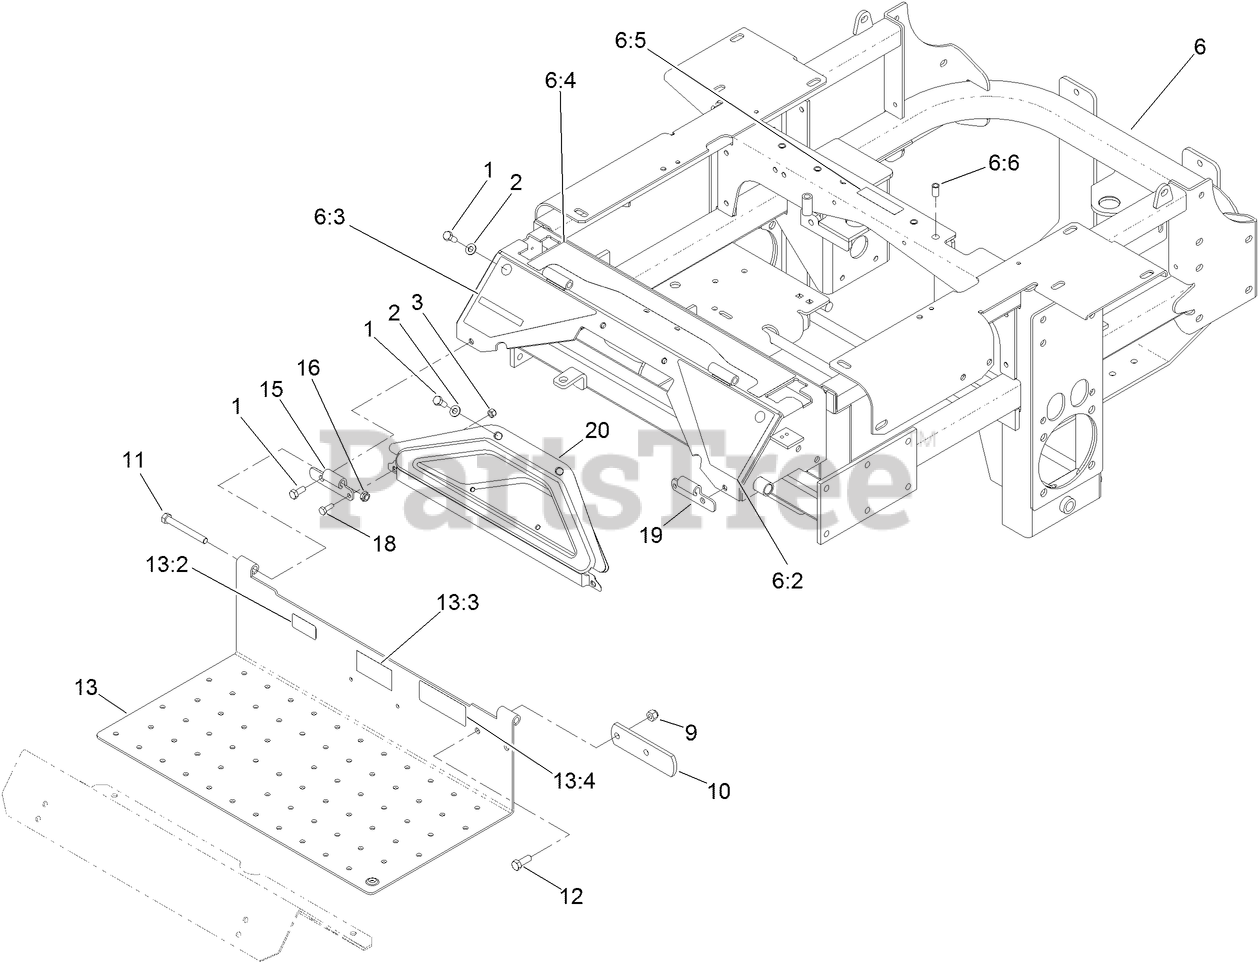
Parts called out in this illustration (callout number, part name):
1	SCREW-HH
2	WASHER-FLAT
3	NUT-LOCK, NI
6	TRACTION FRAME ASM
6:2	DECAL-WARNING
6:3	DECAL-DANGER
6:4	DECAL-CONSOLE, TOP
6:5	DECAL-COVER, MISSING
6:6	NUT-CLINCH
9	NUT-LOCK, NI
10	STOP-BRAKE, PARK
11	SCREW-HH
12	SCREW-HH
13	FLOOR PAN ASM
13:2	DECAL-PROTECTION, EAR
13:3	DECAL-LOCATION, MANUAL
13:4	DECAL-DIESEL, BIO-READY
15	HINGE-FLOORPAN, LH
18	SCREW-HH
19	HINGE-FLOORPAN, RH
20	POCKET
